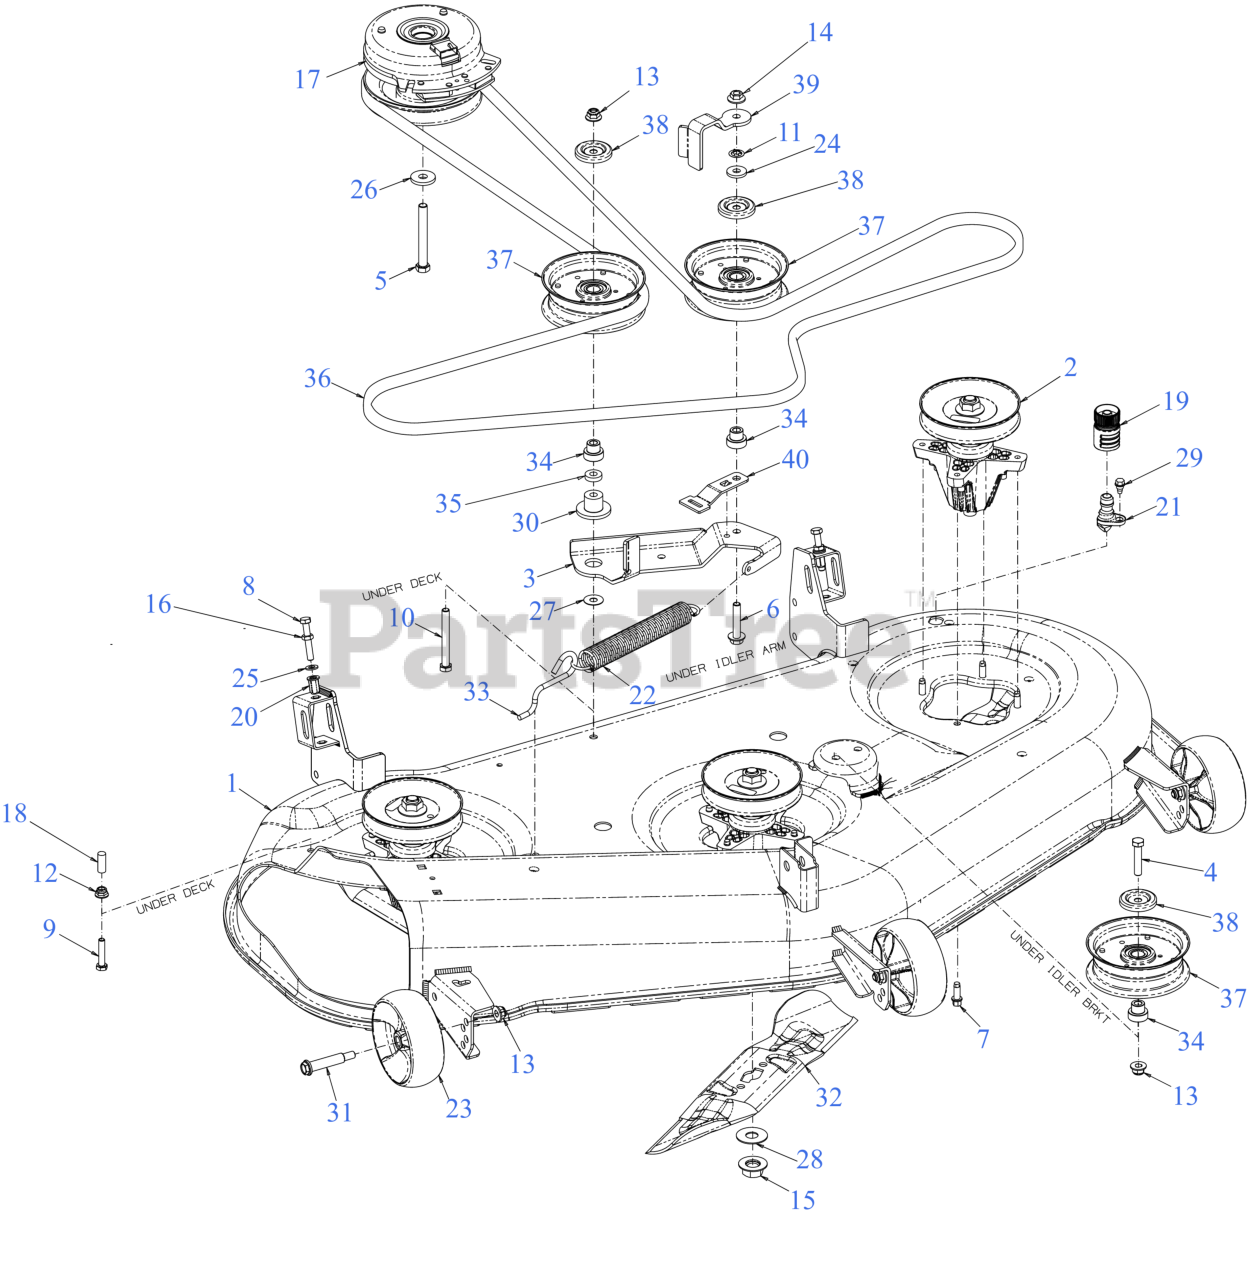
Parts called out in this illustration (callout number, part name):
1	50" DECK SHELL
2	SPINDLE ASSEMBLY (5.37 DIA)
3	DECK IDLER BRACKET
4	HEX SCREW 3/8-16 x 1.75 GR5
5	SCREW 7/16-20 x 3.5 GR5
6	SCREW 3/8-16 x 2.0
7	SCREW 5/16-18 x .875
8	SCREW-FULL THREAD 5/16-18 GR5
9	SCREW 5/16-18 x 1.5 LG
10	SCREW 3/8-16 x 3.25 GR8
12	FLANGE LOCK NUT 5/16-18
14	FLANGE LOCK NUT
15	HEX FLANGE NUT 5/8-18 GR5
17	ELECTRIC PTO CLUTCH
19	WATER NOZZLE ADAPTER
20	NUT RIVET 5/16-18
21	DECK WASH NOZZLE
22	EXTENSION SPRING
23	DECK WHEEL (5.0 DIA x 1.875)
23	Cub Cadet 5" DECK WHEEL (06305A) (W/BOLT)
24	FLAT WASHER .385 x 1.00 x .135
25	FLAT WASHER
26	FLAT WASHER .445 x 1.248 x .170
27	FLAT WASHER
28	FLAT WASHER .635X1.585X.062 HDN
29	SHOULDER SCREW 1/4-20 x .50
30	SHOULDER SPACER
31	SHOULDER BOLT (.50 X 2.0 x 3/8 -16)
32	17.271" BLADE (2IN1) (S SHAPE CENTER HOLE)
32	Cub Cadet 50" HI LIFT BLADE SET (S SHAPE CENTER HOLE)
32	Troy-Bilt 50" HI LIFT BLADE SET (S SHAPE CENTER HOLE)
32	17.271" XTREME BLADE (2IN1) (S SHAPE CENTER HOLE)
32	Cub Cadet 50" XTREME BLADE SET (S SHAPE CENTER HOLE)
32	Troy-Bilt 50" XTREME BLADE SET (S SHAPE CENTER HOLE)
32	17.271" LOW LIFT (S SHAPE CENTER HOLE)
32	Cub Cadet 50" LOW LIFT BLADE SET (S SHAPE CENTER HOLE)
32	Troy-Bilt 50" LOW LIFT BLADE SET (S SHAPE CENTER HOLE)
33	DECK SPRING HOOK
34	SHOULDER SPACER
36	V-BELT B SEC x 143.5 LG
36	Cub Cadet 50" DECK DRIVE BELT
36	Genuine Factory Parts 50" DECK BELT
36	Troy-Bilt 50" DECK DRIVE BELT
37	IDLER PULLEY 4.50" DIA
38	IDLER PULLEY CAP
39	BELT KEEPER
